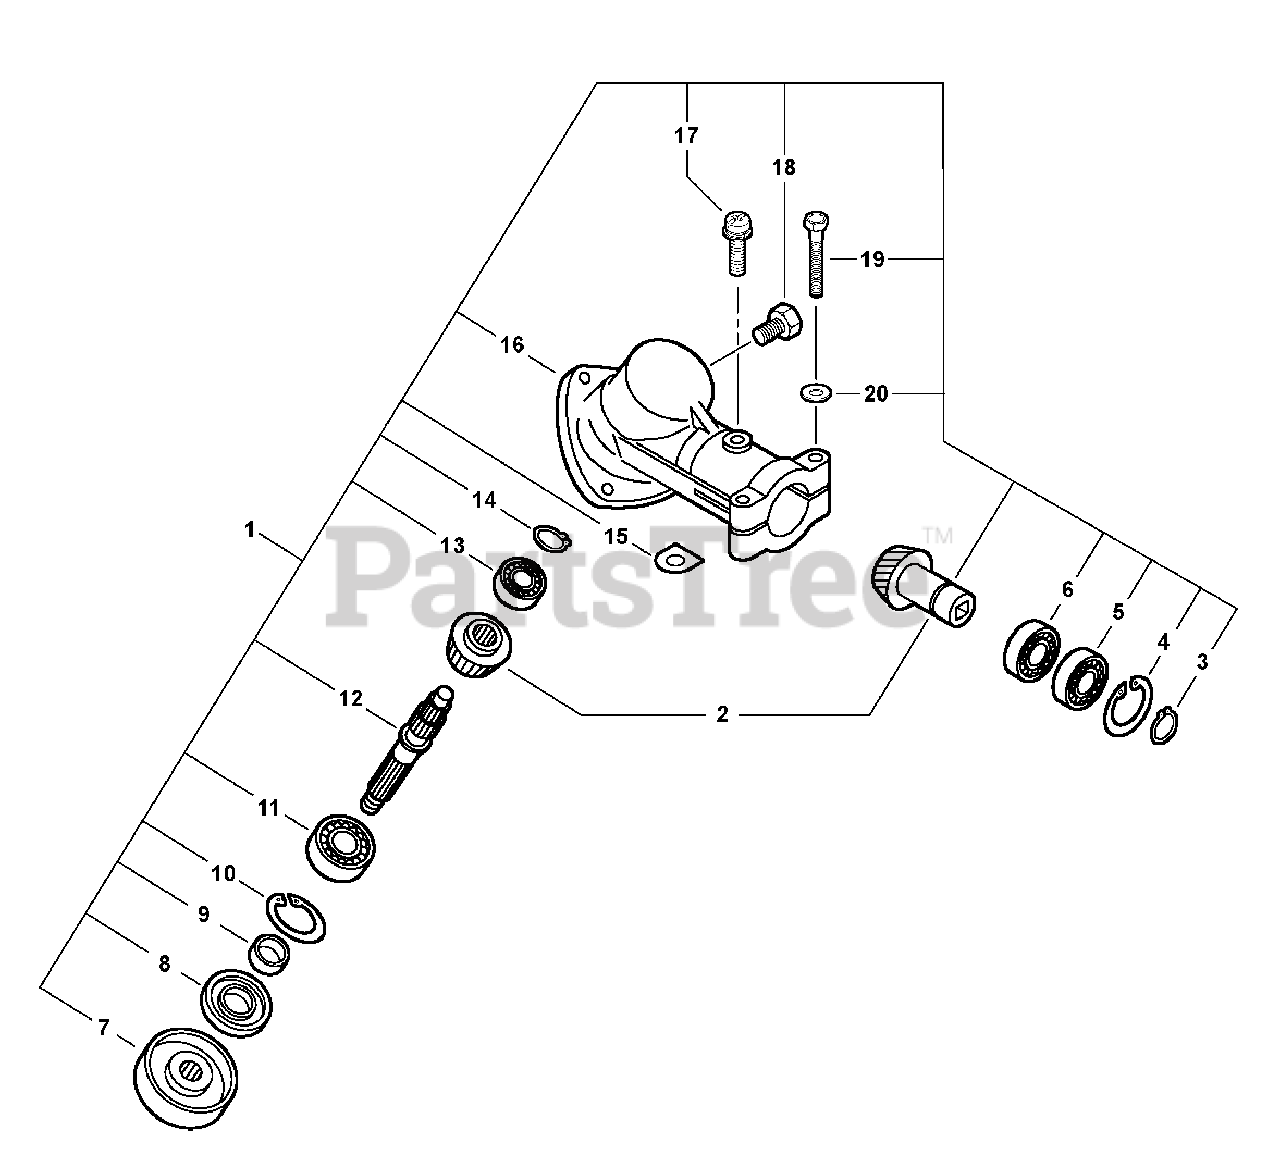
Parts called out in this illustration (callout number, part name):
1	GEAR CASE ASSY
2	GEAR SET
3	RING, SNAP Ø10
4	RING, SNAP Ø22
5	BEARING, BALL 6900Z
6	BEARING, BALL 6900
7	PLATE, ADAPTOR - UPPER
8	SEAL, OIL 22
9	SPACER 11.8×15×9
10	RING, SNAP Ø32
11	BEARING, BALL - 6201 C3
12	SHAFT, GEAR
13	BEARING, BALL 609
14	RING, SNAP Ø12
16	HOUSING, GEAR CASE
17	SCREW 5×10
18	BOLT M8×8
19	BOLT 5×35 SP
20	WASHER, FLAT 5.5×10×0.8
